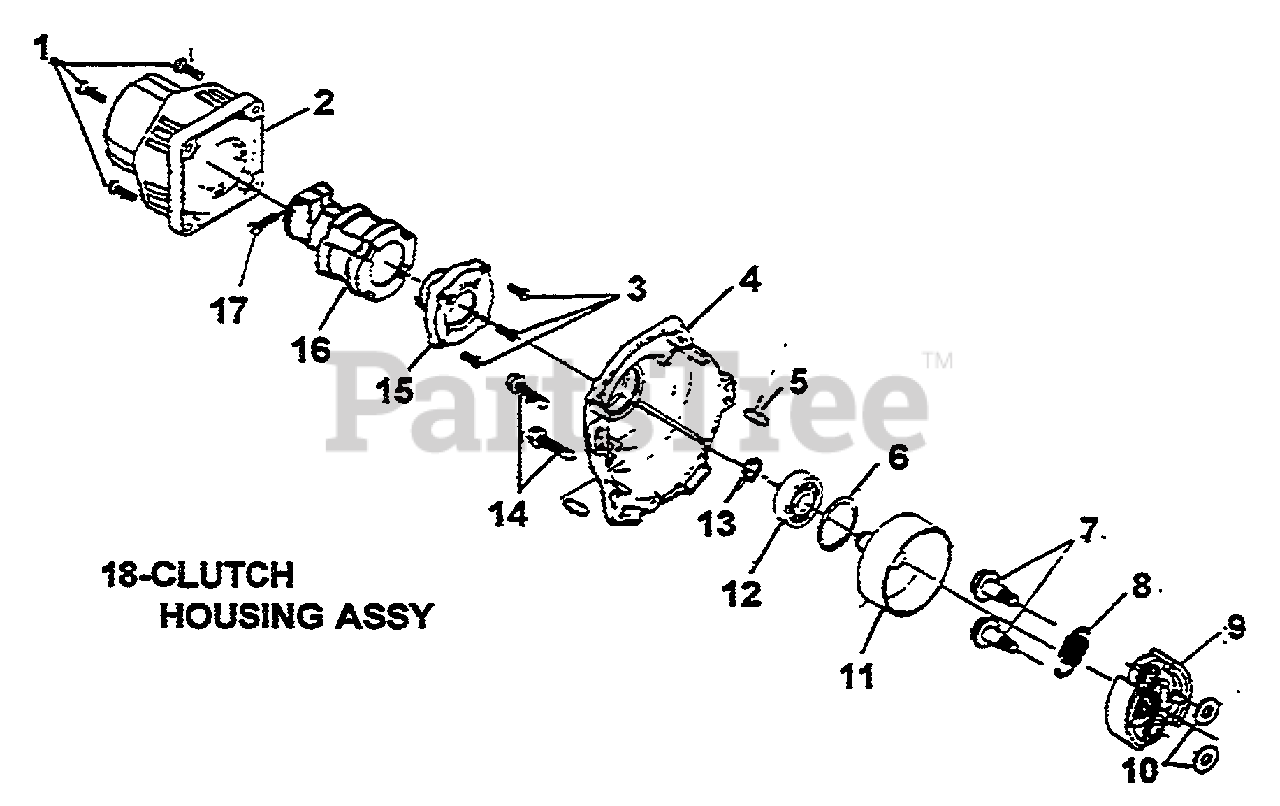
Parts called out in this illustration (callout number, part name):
1	BOLT & WASHER
2	CLUTCH CASE
4	CASE COVER
5	PIN, DOWEL
6	SNAP RING
7	BOLT, CLUTCH
8	SPRING, CLUTCH
9	CLUTCH KIT
10	WASHER
11	CLUTCH DRUM
13	SNAP RING
14	BOLT & WASHER
15	BEARING COVER
16	INSERT RING
18	CLUTCH HOUSING ASSY
